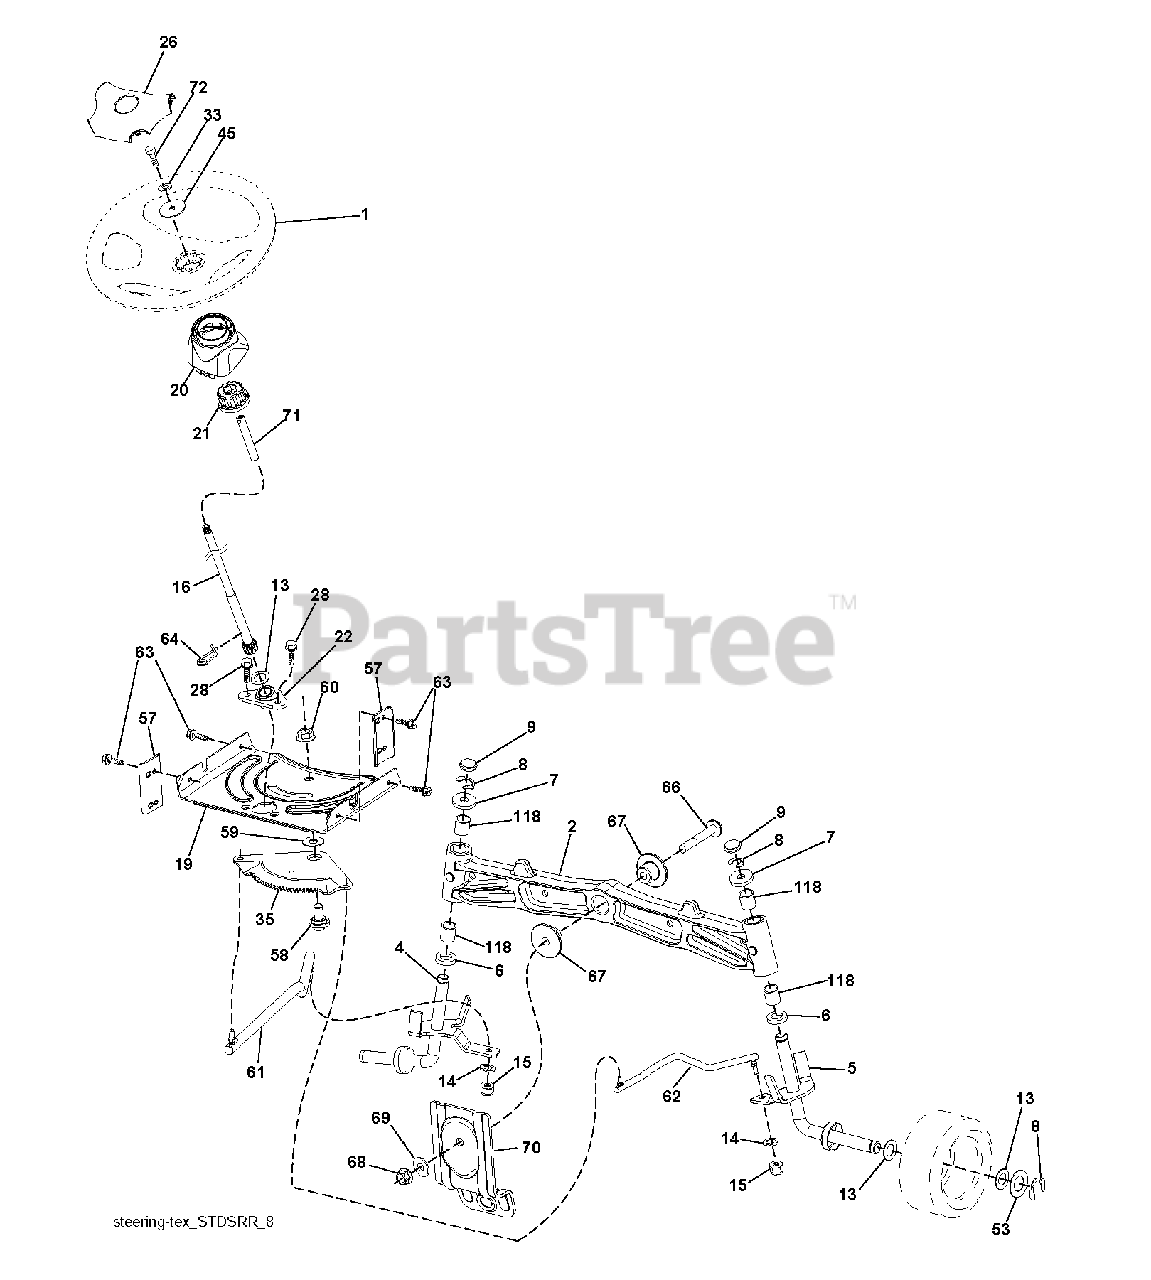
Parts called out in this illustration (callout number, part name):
1	WHEEL.STEERING.STDSRR.BLK/OV
2	AXLE.SVC.ASM CAST IRON.TEX
4	SPINDLE.WELDED.LH.15"TEX
5	SPINDLE.WELDED.RH.15"T
8	RING CLIP
9	CAP.SPINDLE
14	WASHER, LOCK 3/8
15	NUT CROWNLOCK 3/8-24
16	SHAFT STEERING
19	PLATE.STEER.DDL.NLT/NG
20	BOOT.STEERING.PREDATOR.LT.BLAC
21	ADAPTER, WHEEL STNG..
22	BUSHING.ASM.STEERING.A
26	CAP.WHL.STRNG.STDSRRD.SRS.BLK
28	SCREW, 3/8-16X3/4
33	LOCKWASHER
35	GEAR.SECTOR.PLATE.DDL.
45	WASHER.11/32
53	WASHER.HARDENED
57	BRACKET.UPSTOP.TEX
58	BOLT.SHOULDER.SECTOR.P
59	WASHER.THURST.SECTOR.S
60	NUT FLANGE LOCK 5/8-11
61	DRAGLINK.LH.BALLSTUD.D
62	DRAGLINK.RH.BALLSTUD.D
63	SCREW
64	RETAINER.CLIP.SPRING.S
66	BOLT HEX FGHD 7/16-14 X 3 SERR
67	BUSHING.PM.FRONT AXLE
68	NUT.LOCK.FLANGE.7/16
69	WASHER.1.5X.505X.118
70	BRKT.DECK.SUSPENSION.F
71	SHAFT EXTENSION STEERING
72	BOLT YT
74	BRNG T
118	BUSHING, AXLE CAST
